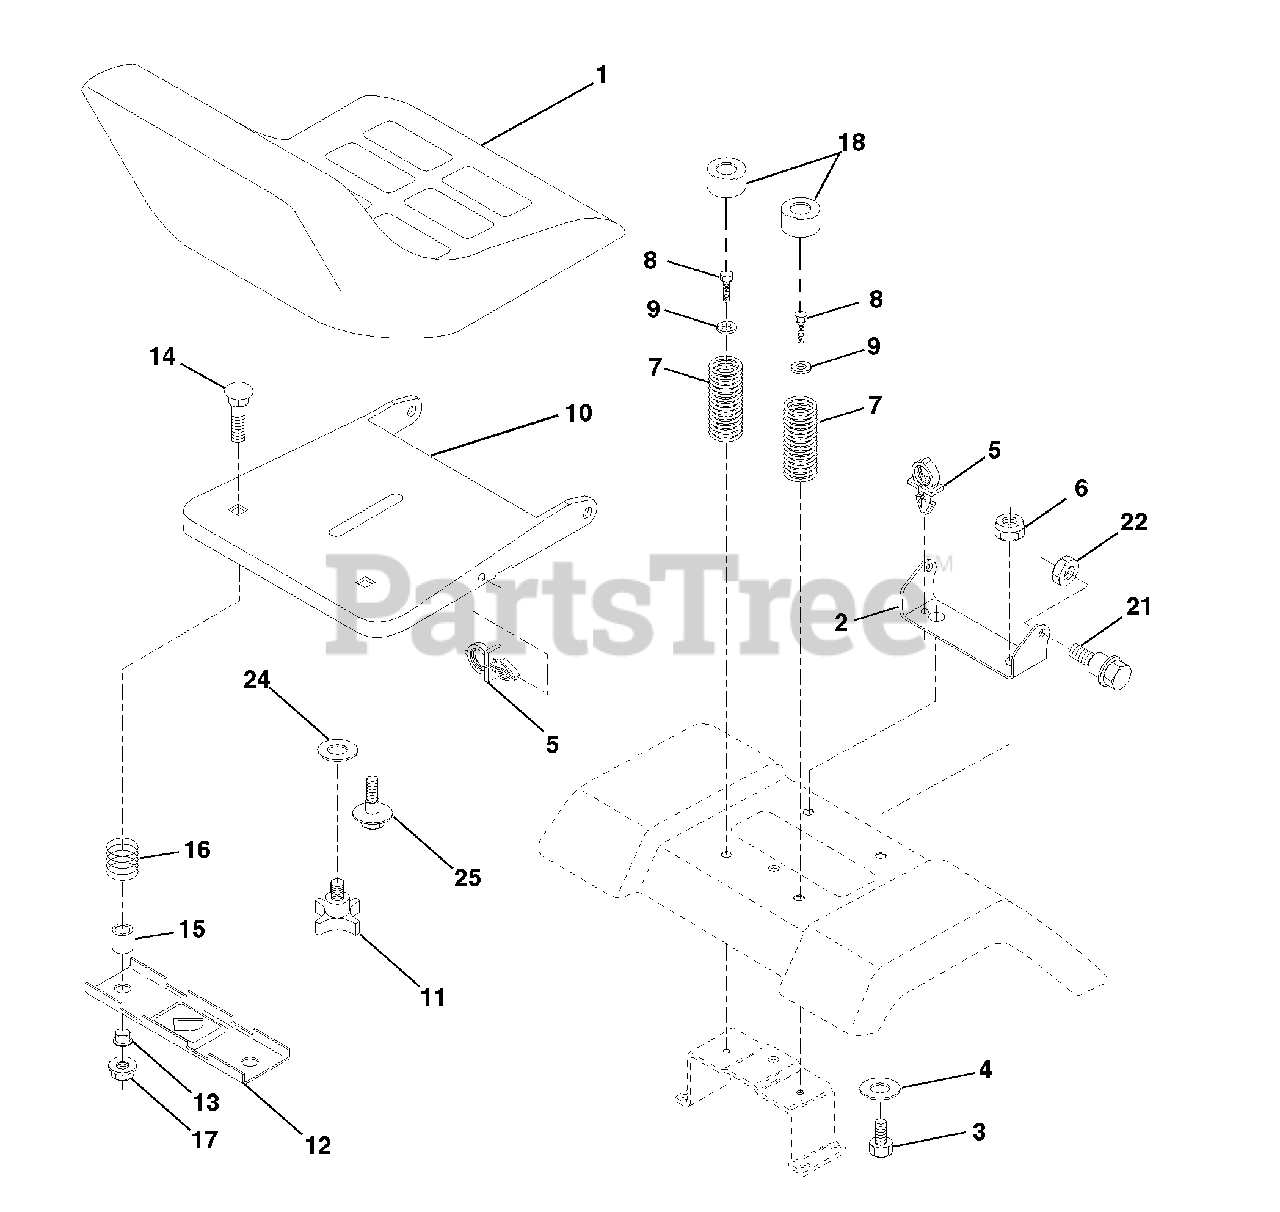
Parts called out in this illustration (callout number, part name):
1	Seat
2	Bracket Pivot Seat 8 720
3	Bolt Fin Hex 3/8-16unc X 1
4	Washer 13/32 X 1 X 10 Ga
5	Clip Push-In
6	Nut Hex w/Ins. 3/8-16 Unc
7	Spring Seat Cprsn 2 250 Blk Zi
8	Screw Thdrol 3/8-16 X 1 Ty-tt
9	Washer 13/32 X 1 X 14 Ga.
10	Pan Seat
11	Knob Seat 1/2-13 Unc
12	Bracket Mounting Switch
13	Bushing Snap Blk Nyl 50 Id
14	Bolt Rdhd Sqnk 1/4-20x1-1/2
15	Spacer Split 28 x .88 Zinc
16	Spring Cprsn Plate
17	Nut Lock 1/4 Lge Flg Gr 5 Zinc
18	Cap Spring Seat
21	Bolt Shoulder 5/16-18 Unc
22	Nut Hex Lock W/Ins 5/16-18
24	Washer 17/32 X 1-3/16 X 12 Ga.
25	Bolt Shoulder 5/16-18 X 62
